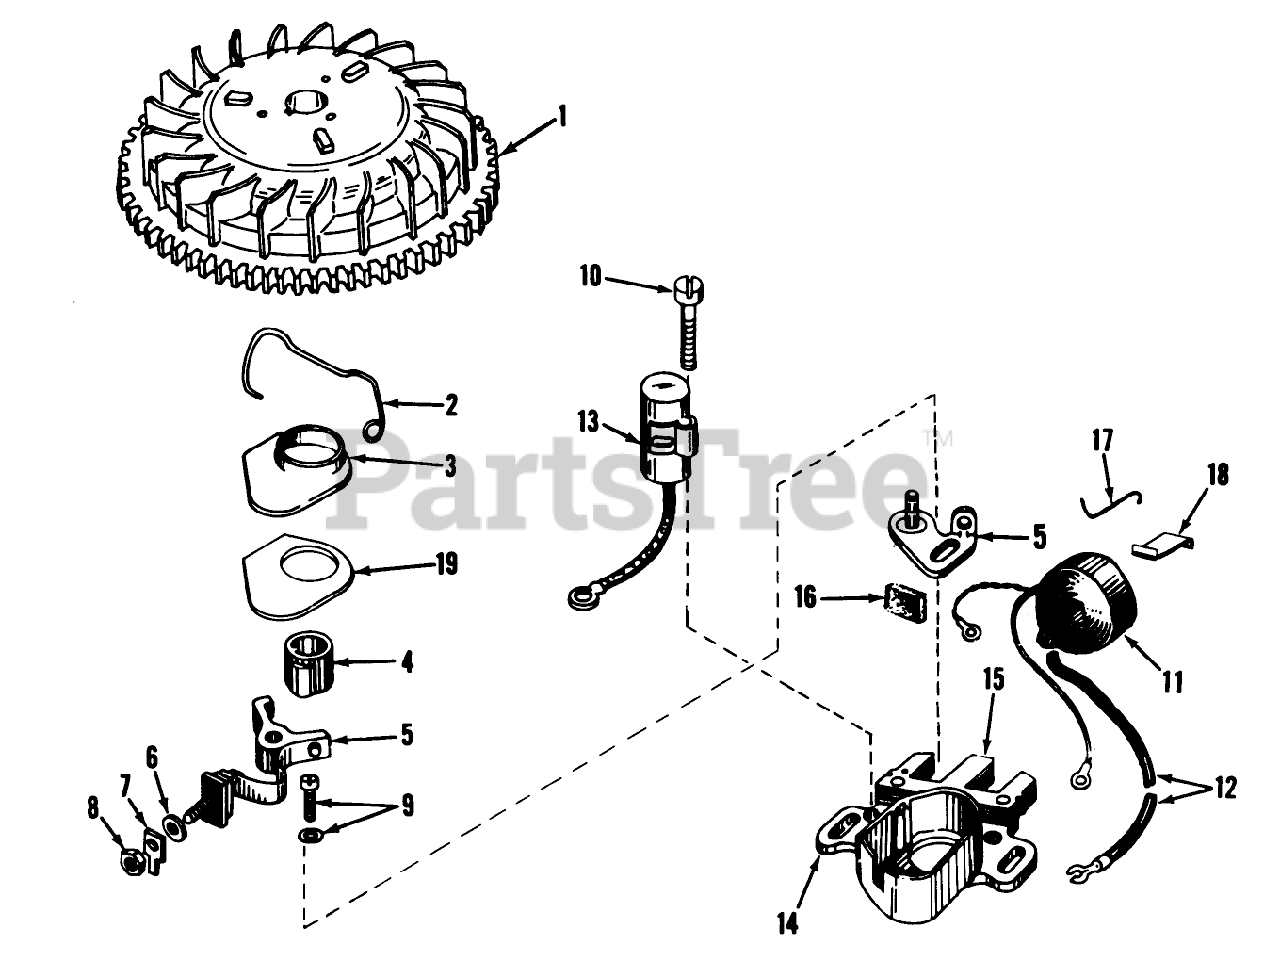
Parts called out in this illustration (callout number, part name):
1	FIywheel
2	Spring Breaker Box
3	Cover, Dust
4	Cam, Breaker
5	Breaker Assy.
6	Washer
7	Terminal, Ground
8	DECAL
9	Breaker Screw
10	Condenser Screw
11	Coil Assy. (Incl. No. 12)
12	Wire, Lead
13	Condenser
14	Core Plate
15	Stator Assy., (Incl. Nos. 2, 3, 5 thru 14 16 thru 19)
16	Felt,Cam Wiper
17	Clip, Coil
18	Spring Coil Wedge
19	Gasket Dust Cover
